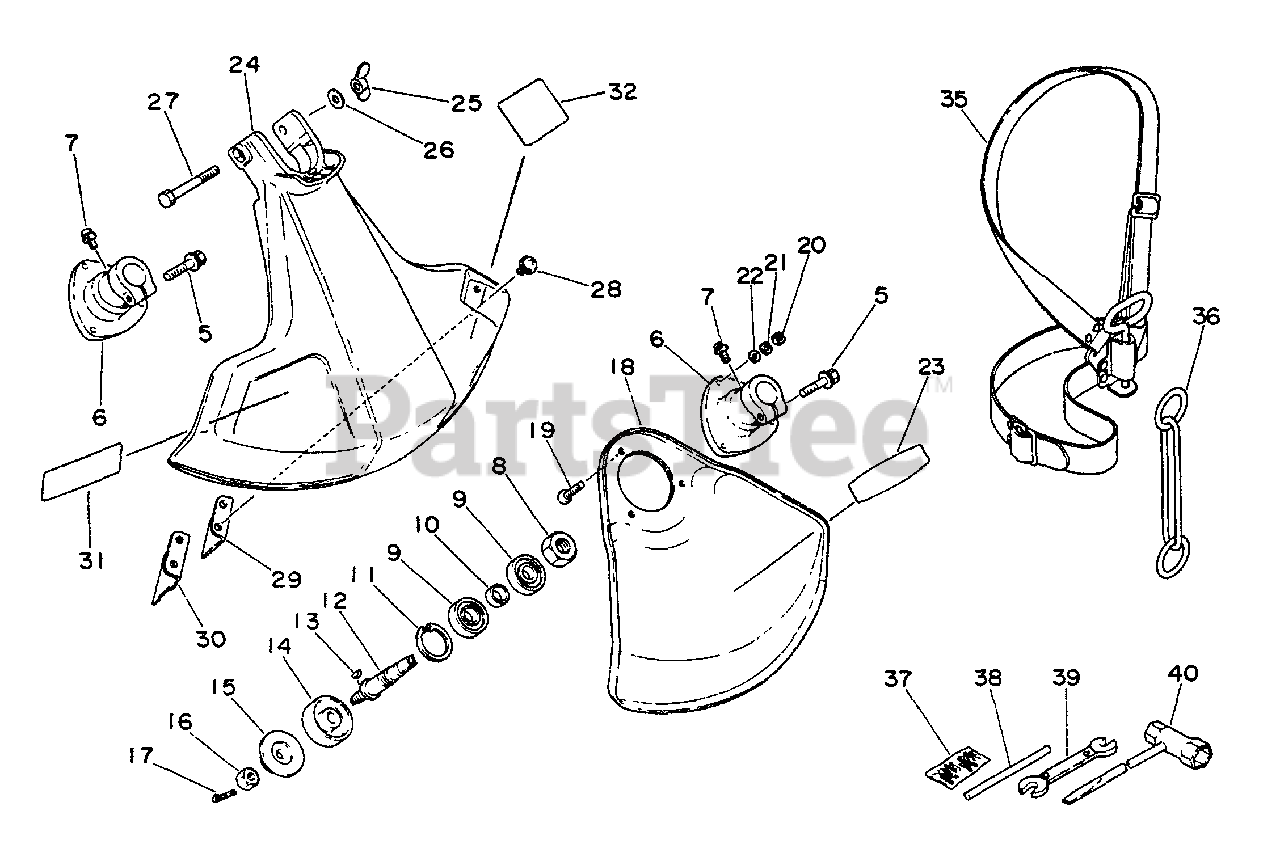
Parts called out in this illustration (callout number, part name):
5	BOLT - 5×25
6	GEAR CASE ASSY
6	CASE, BEARING
7	SCREW 4×10
8	NUT 12 L.H.
9	BEARING, BALL 6001 DDU
11	RING, SNAP 28
12	GEAR, SHAFT
14	PLATE, ADAPTER - UPPER
15	PLATE, ADAPTER - LOWER
17	PIN, COTTER 2×22
18	SHIELD
19	SCREW 4×18
21	WASHER, SPRING 4 MM
22	WASHER 4 MM
23	LABEL - ECHO
24	SHIELD
25	NUT, WING 6
26	WASHER 6.5×11.5×0.8
27	BOLT - 6×50
28	SCREW 5×16
29	KNIFE, TRIMMER LINE
30	PROTECTOR
31	LABEL, ECHO
32	LABEL - CAUTION
35	SHOULDER STRAP ASSY
36	HOOK
37	PIN, COTTER 2×22 (PKG. OF 10)
38	TOOL, LOCKING 5×120 MM
39	SPANNER 8×10
40	T-WRENCH 17x-19 L200
